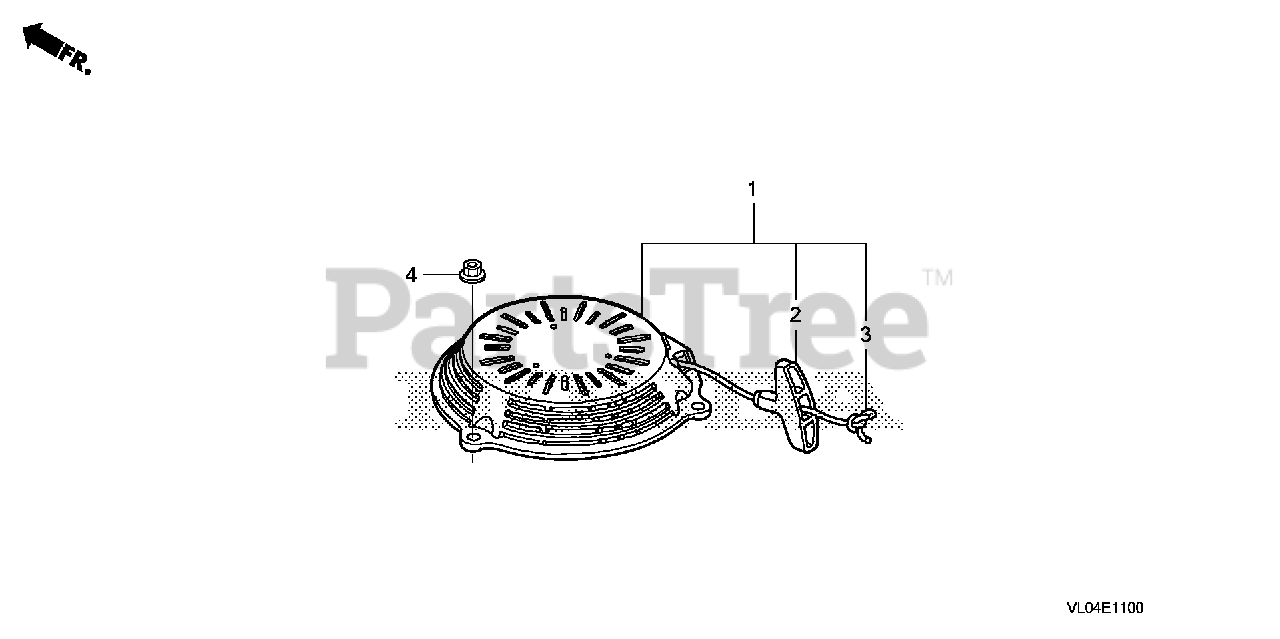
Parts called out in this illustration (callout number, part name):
1	STARTER ASSY., RECOIL *R280* (LONG ROPE) (POWER RED)
2	KNOB, RECOIL STARTER
3	ROPE, RECOIL STARTER (LONG TYPE)
4	NUT, FLANGE (6MM)
